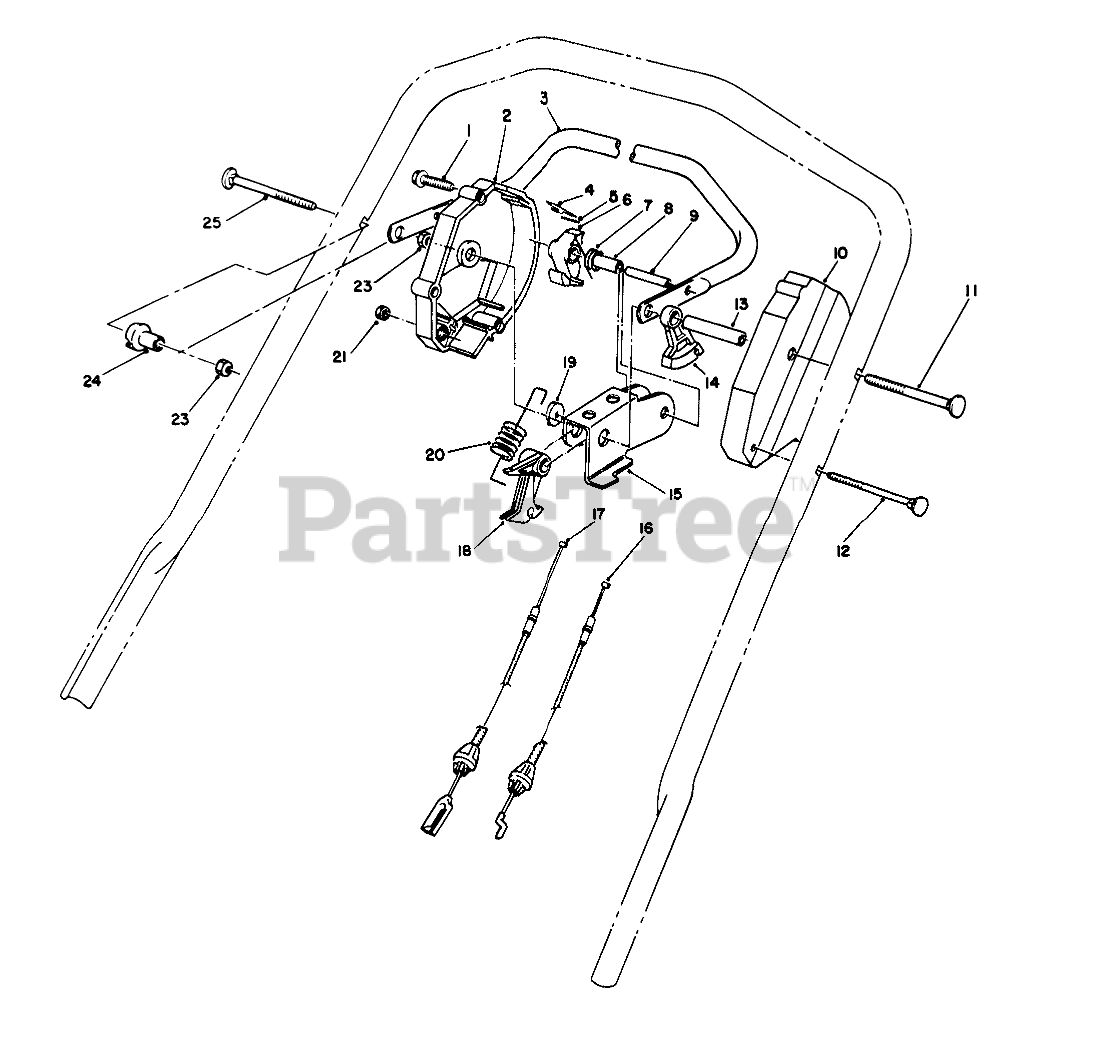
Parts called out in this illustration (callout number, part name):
1	SCREW-HWHTF
2	Housing-Control
3	Bar-Control
4	SPRING-LEAF
5	PIN-INSERT
6	HOOK-CONTROL
7	SPRING-TORSION
8	SPACER
9	PIN-ROLL, SLOTTED
10	HOUSING-CONTROL, LH
11	Screw-Handle
12	HANDLE SCREW
13	TUBING-SPACER
14	LEVER-TRACTION
15	ROCKER
16	TRACTION CABLE
17	BBC CABLE ASSEMBLY
18	LEVER-CABLE
19	WASHER-NYLON
20	SPRING-DETENT
21	NUT-HEX
23	NUT-LOCK, NI
24	SPACER-SUPPORT
25	SCREW-HANDLE
